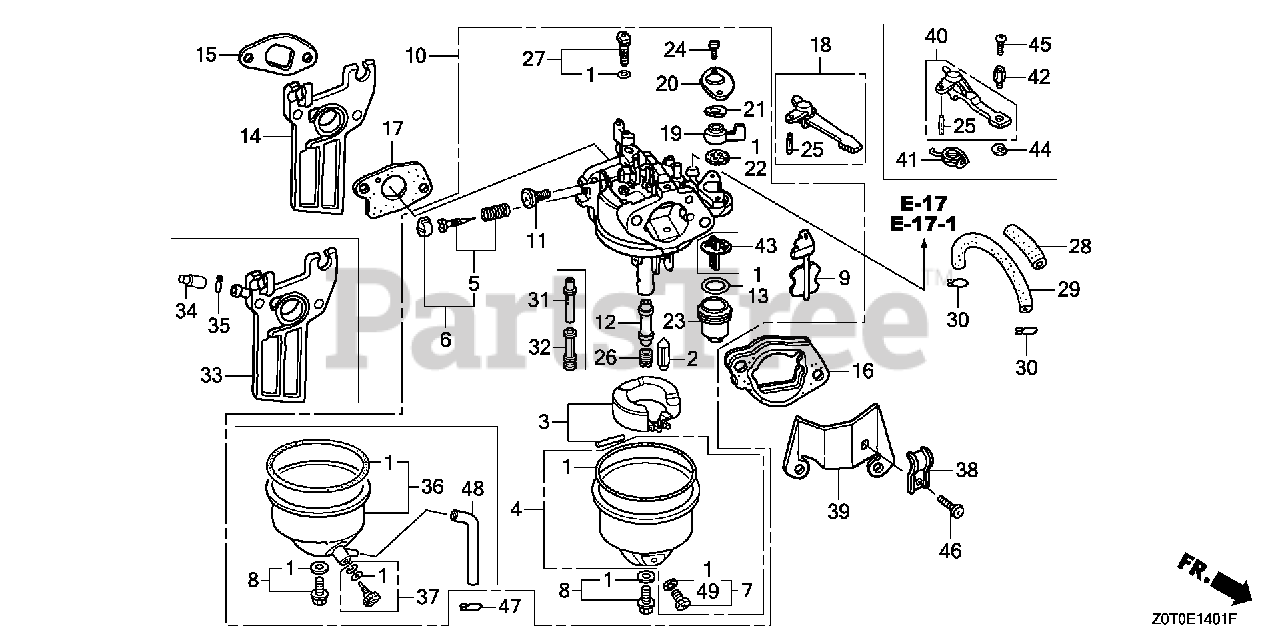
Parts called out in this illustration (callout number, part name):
1	GASKET SET
2	VALVE SET, FLOAT (SEAT NOT INCLUDED)
3	FLOAT SET (CARBURETOR NO.)
4	CHAMBER SET, FLOAT
6	SCREW SET, PILOT (CARBURETOR NO.)
7	SCREW SET, DRAIN
8	SCREW SET
9	CHOKE SET (CARBURETOR NO.)
10	CARBURETOR ASSY. (BE65Q A)
11	SCREW, THROTTLE STOP
12	NOZZLE, MAIN
13	GASKET, FUEL STRAINER CUP
14	INSULATOR, CARBURETOR
15	GASKET, INSULATOR
16	SPACER, CARBURETOR
17	GASKET, CARBURETOR
18	LEVER, CHOKE (STD)
19	LEVER, PETCOCK
20	PLATE, LEVER SETTING
21	SPRING, PETCOCK LEVER
22	GASKET, PETCOCK
23	CUP, FUEL STRAINER
24	SCREW, PAN (3X6)
25	PIN, SPRING (2X12)
26	JET, MAIN (#65)
26	JET, MAIN (#68)
26	JET, MAIN (#70)
27	JET SET, PILOT (#35)
28	RUBBER, SUPPORTER
29	BULK HOSE, FUEL (4.5X3000) (4.5X300)
30	CLIP, TUBE (B8)
